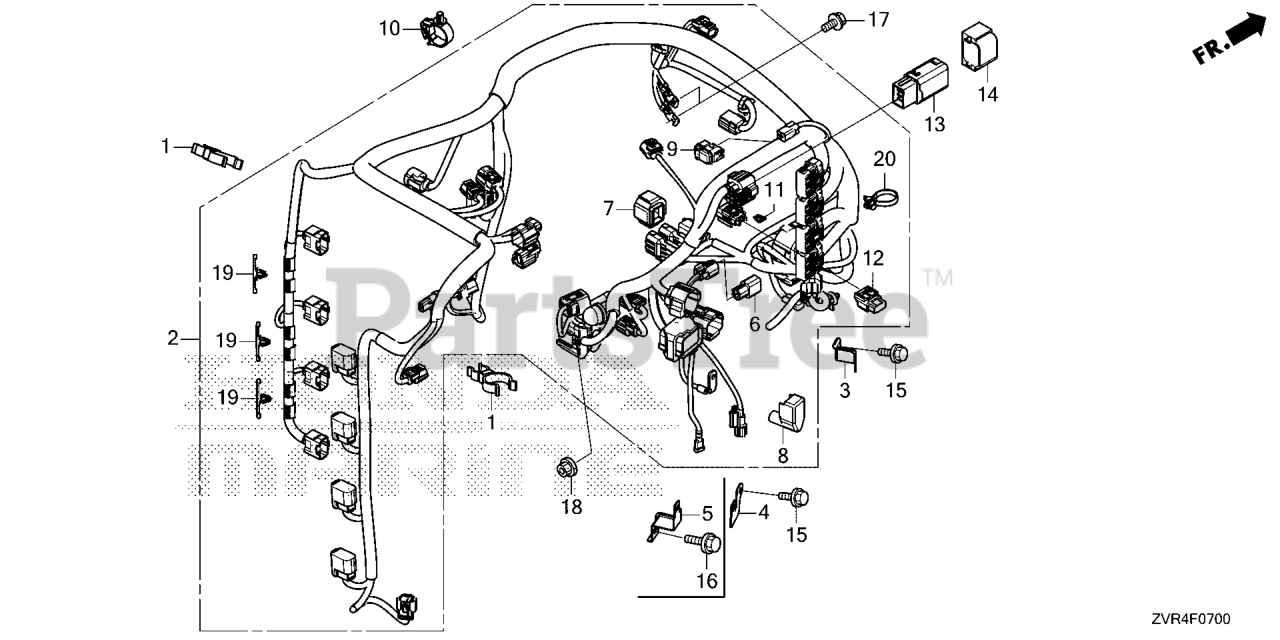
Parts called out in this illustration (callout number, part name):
1	CLAMP, HOSE
2	HARN, MAIN WIRE
3	STAY, CONNECTOR
4	STAY, CONNECTOR
6	TERMINATOR ASSY.
7	SUSPENSION, CONNECTOR
8	COVER B, TERMINAL (L)
9	CAP, DUMMY (WPC 4P 090 M) (RED)
10	CLAMP, ENGINE SUB-WIRE
11	FUSE, BLADE (3A)
12	COVER ASSY., FUSE
13	RELAY ASSY., SENSING
14	CUSHION, RELAY
15	BOLT, FLANGE (6X14)
17	BOLT, FLANGE (6X12)
18	NUT-WASHER (6MM)
19	CLIP, WIRE HARNESS
20	CLIP, HARNESS BAND (145MM) (BLACK)
